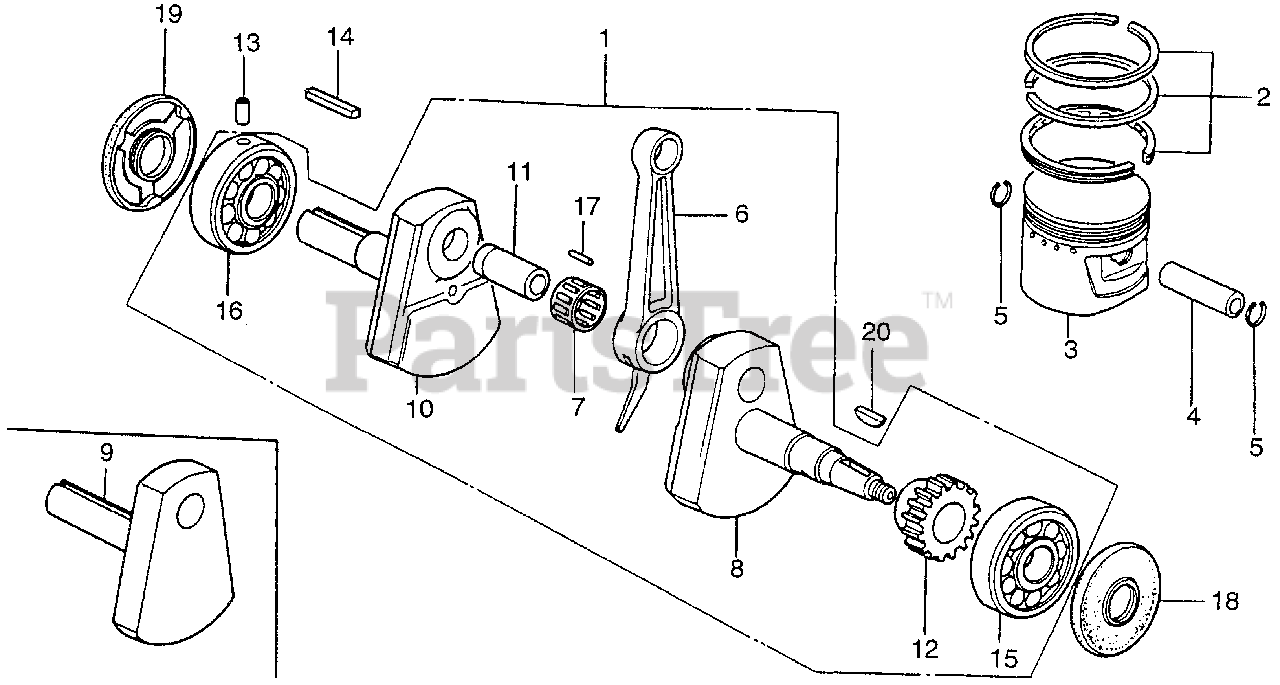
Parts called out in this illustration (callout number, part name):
1	CRANKSHAFT ASSY.
2	RING SET, PISTON (STD)
2	RING SET, PISTON (OS 0.25) (NOT AVAILABLE)
2	RING SET, PISTON (OS 0.50) (NOT AVAILABLE)
2	RING SET, PISTON (0.75) (NOT AVAILABLE)
3	PISTON (STD) (NOT AVAILABLE)
3	PISTON (OS 0.25)
3	PISTON (OS 0.50) (NOT AVAILABLE)
3	PISTON (0.75)
4	PIN, PISTON
5	CLIP, PISTON PIN (19MM)
6	ROD, CONNECTING (NOT AVAILABLE)
7	RETAINER, ROLLER
8	CRANKSHAFT, R. (NOT AVAILABLE)
9	CRANKSHAFT, L.
10	CRANKSHAFT, L.
11	PIN, CRANK (N/A: SEE ASSEMBLY)
12	GEAR, TIMING
13	PIN, KNOCK (7X12) (NOT AVAILABLE)
14	KEY (7X7X33)
15	BEARING, RADIAL BALL (6306S)
16	BEARING, BALL (6306)
17	ROLLER, ROD (3X16)
18	OIL SEAL (30759) (NOT AVAILABLE)
19	OIL SEAL (PJ30779)
20	KEY, SPECIAL WOODRUFF (25X18)
